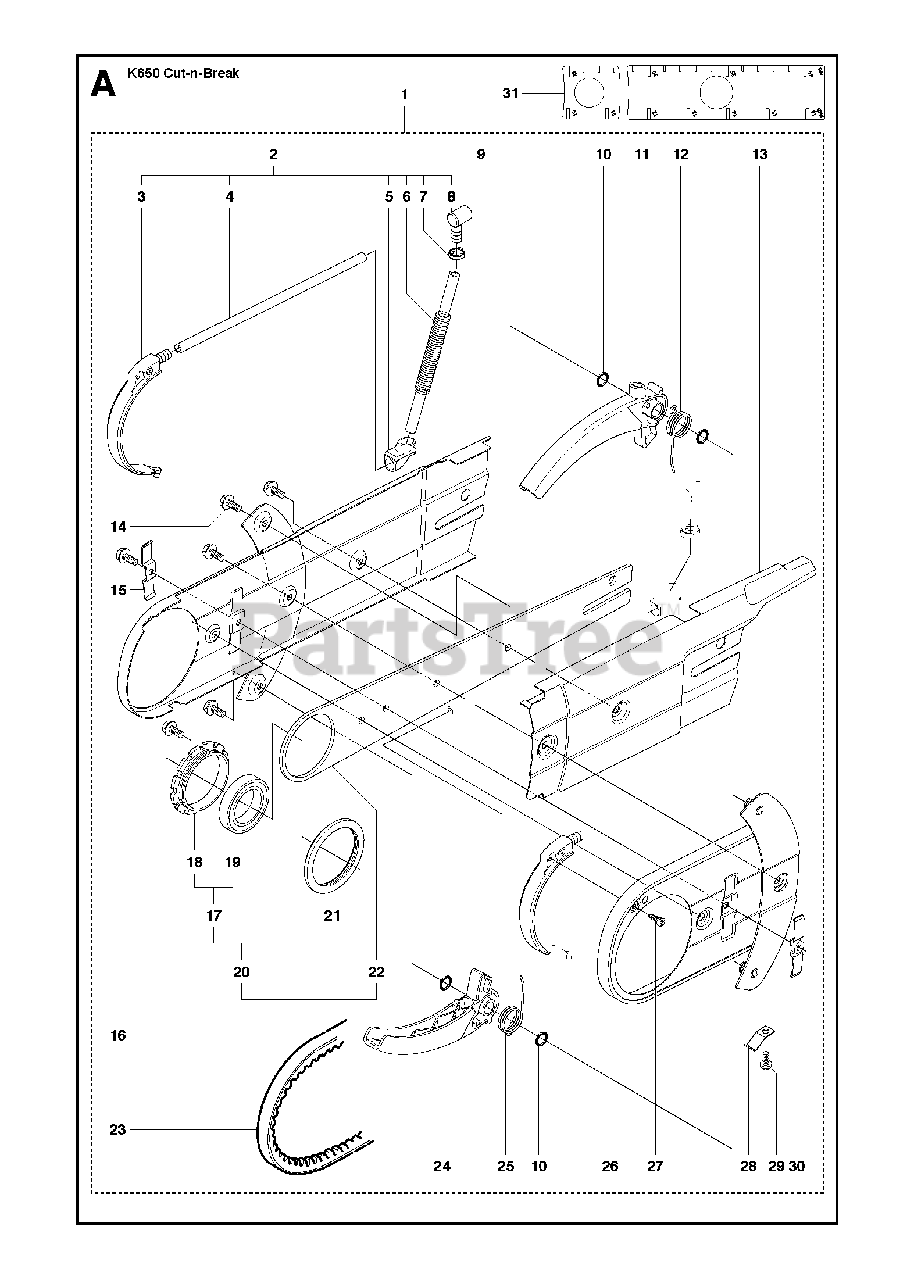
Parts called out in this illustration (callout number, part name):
1	CUTTER ARMIncl. 2, 9 - 16, 23 - 30
2	HOSEIncl. 3 - 8
4	HOSE
6	PROTECTIVE SPRING
9	BELT GUARD
14	SCREW EHHFM
15	DEFLECTION LIMITER
16	BARIncl. 20, 22
17	BEARING CAGEIncl. 18, 19
18	BEARING CAGE
27	SCREW CCRPANT
29	SCREW CRPANM
30	DEFLECTION LIMITER
